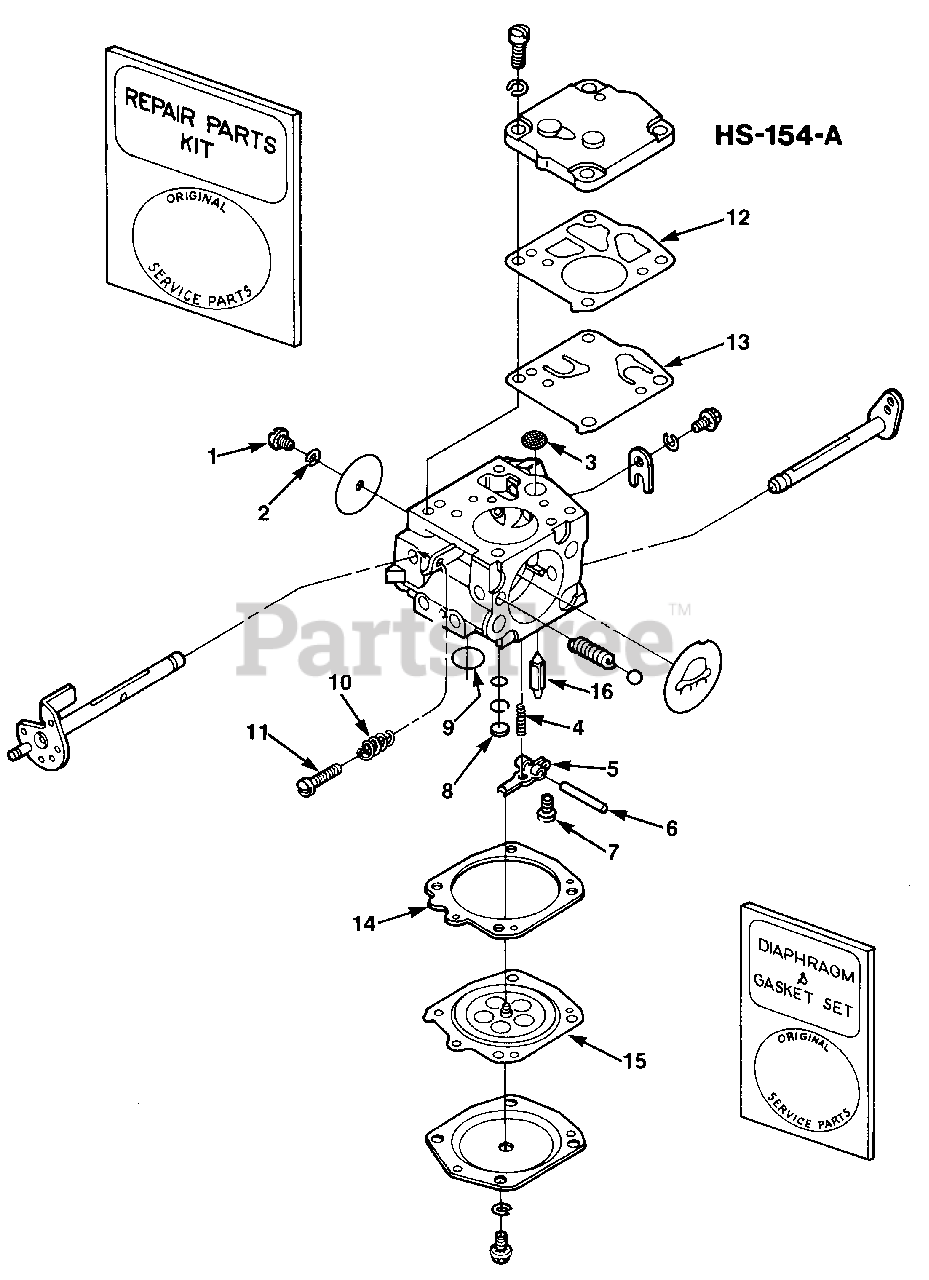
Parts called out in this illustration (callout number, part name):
1	REPAIR KIT
2	REPAIR KIT
3	REPAIR KIT
4	REPAIR KIT
5	REPAIR KIT
6	REPAIR KIT
7	REPAIR KIT
8	REPAIR KIT
9	REPAIR KIT
10	REPAIR KIT
11	REPAIR KIT
12	REPAIR KIT
13	REPAIR KIT
14	REPAIR KIT
15	REPAIR KIT
16	INLET NEEDLE (Not included in repair kit)
